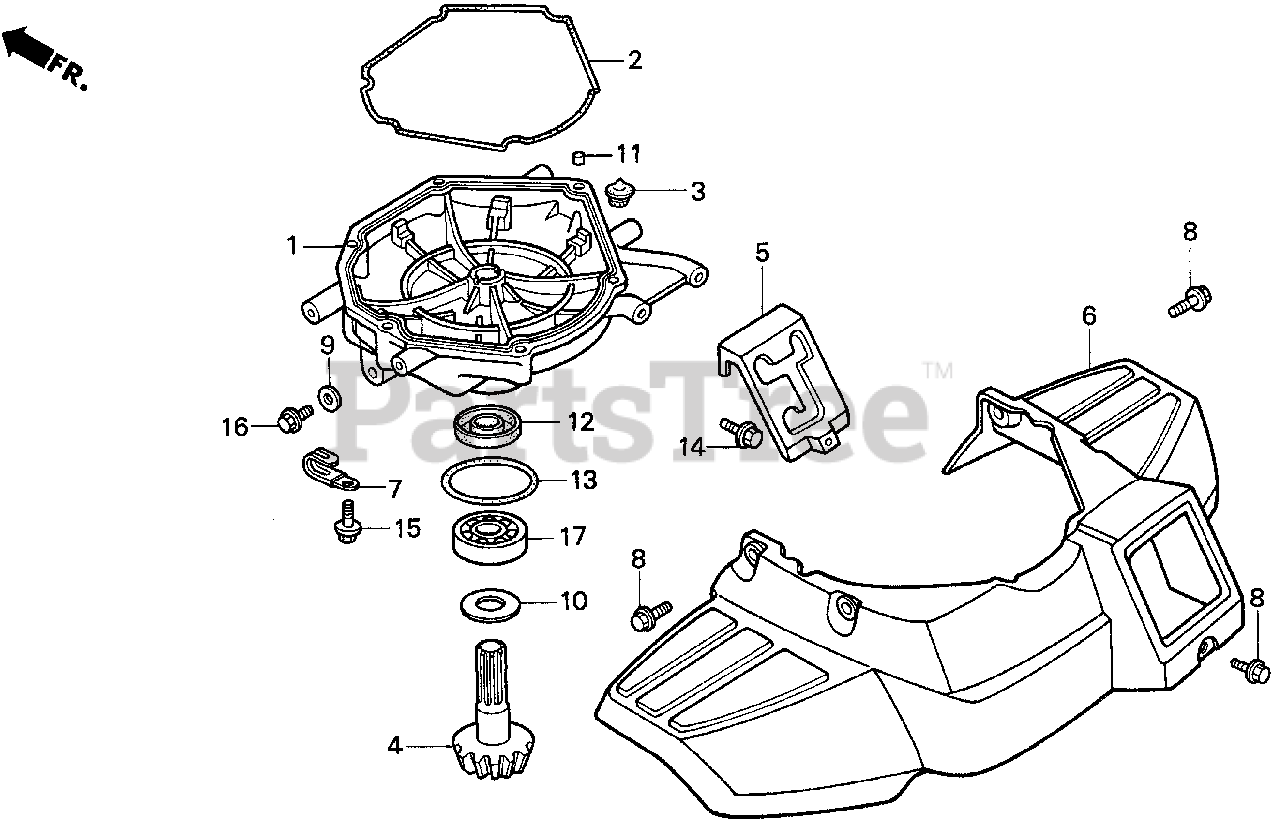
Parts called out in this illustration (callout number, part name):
1	CASE, REDUCTION
2	O-RING (208MM)
3	CAP, TRANSMISSION OIL
4	PINION, BEVEL
5	COVER, CHANGE GUIDE
6	FENDER, MAIN *R8* (BRIGHT RED)
7	CLIP, TUBE
8	BOLT, FLANGE (6MM)
9	WASHER (10.5MM)
10	WASHER, BEVEL GEAR
11	PIN, DOWEL (8X12)
12	OIL SEAL (17X32X5)
13	O-RING (41.7X3.5)
14	BOLT, FLANGE (6X14)
15	BOLT, FLANGE (6X45)
16	BOLT, FLANGE (10X16)
17	BEARING, RADIAL BALL (6203)
